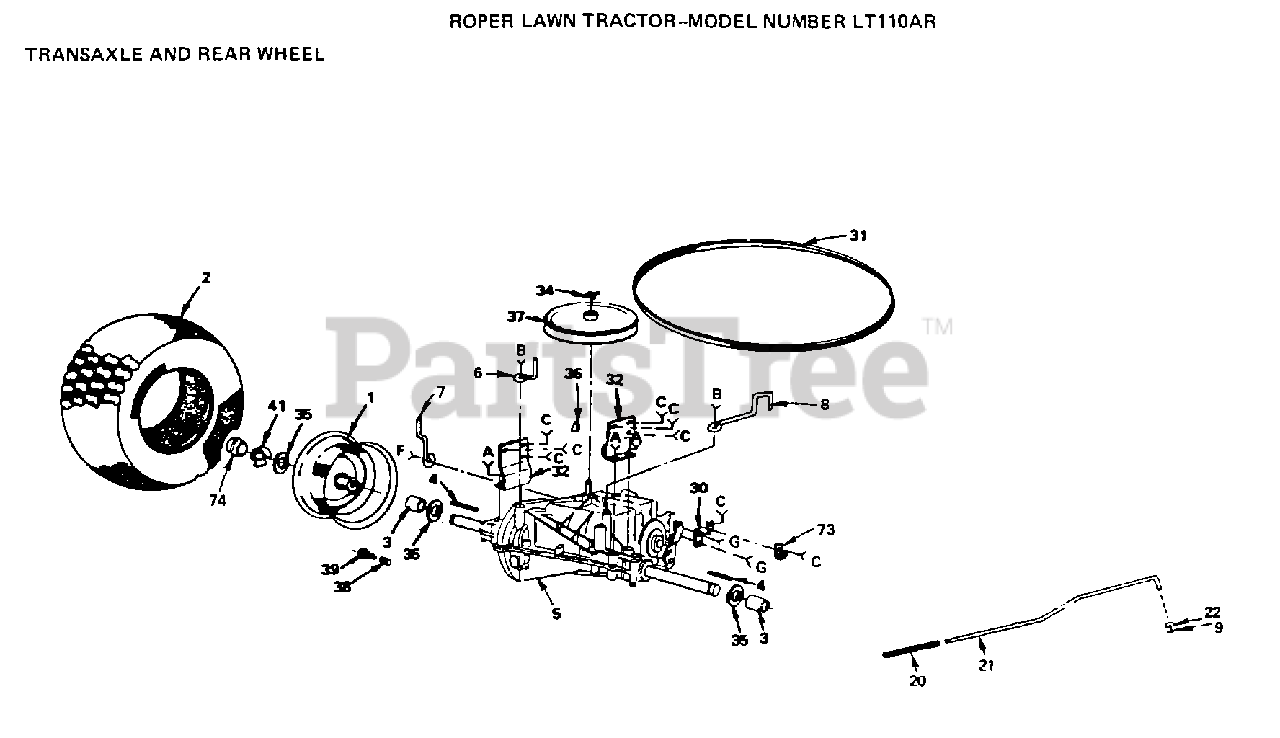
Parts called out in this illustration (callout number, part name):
3	WHEEL SPACER LT
6	BELT SNUBBER T
8	RETAINER, BELT
9	COTTER PIN
22	WASHER
30	STRAP - TORQUE
34	KLIP RING
37	PULLEY-INPUT LT
38	VALVE CAP
39	VALVE STEM LT
41	E-RING LT
73	INSUL CLIP T
